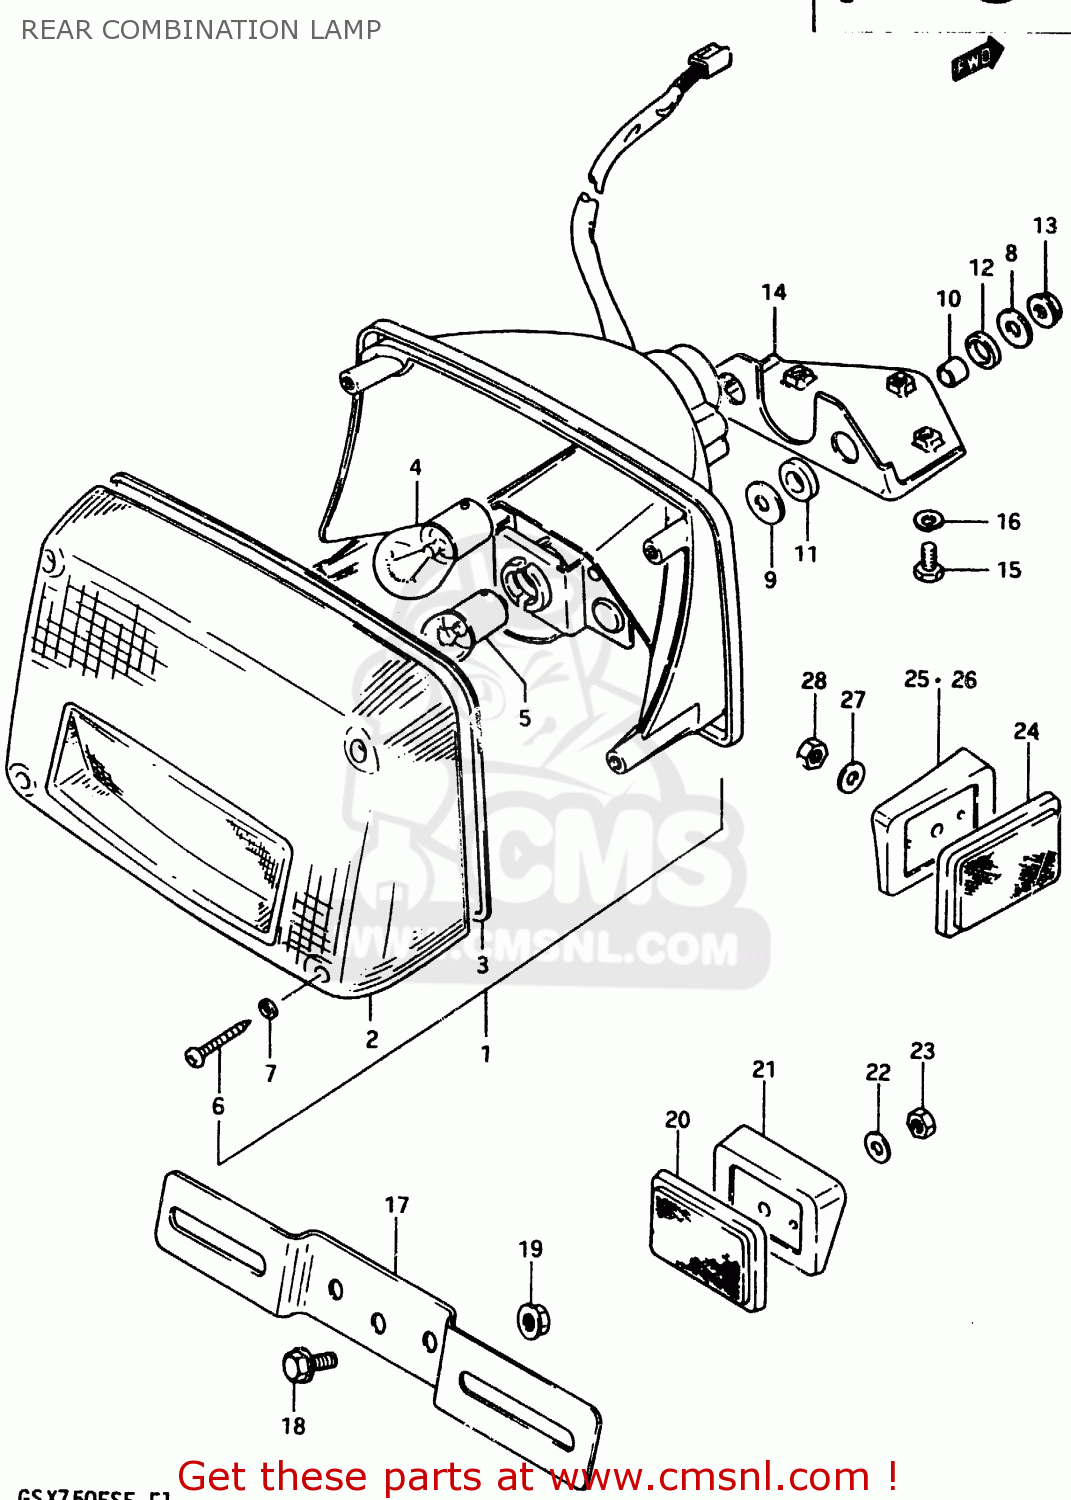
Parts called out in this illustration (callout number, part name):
1	LAMP ASSY,RR C
2	LENS
3	GASKET (NAS)
4	BULB(12V23W)
5	BULB
6	SCREW,REAR COMBINATION LAMP
7	GASKET (NAS)
8	WASHER
9	WASHER(6,5X22X1.6)
10	SPACER(6.1X9X7.5)
11	CUSHION
12	CUSHION
13	NUT
14	BRACKET,REAR COMBINATION LAMP
15	BOLT
16	WASHER,LOCK
17	PLATE,RR LICENSE
18	BOLT
19	NUT
20	REFLEX REFLECTOR,RR
21	SPACER
22	WASHER(5.2X16X1)
23	NUT
24	REFLECTOR,REFLEX
25	SPACER, RH
26	SPACER, LH
27	WASHER(5.2X16X1)
28	NUT
